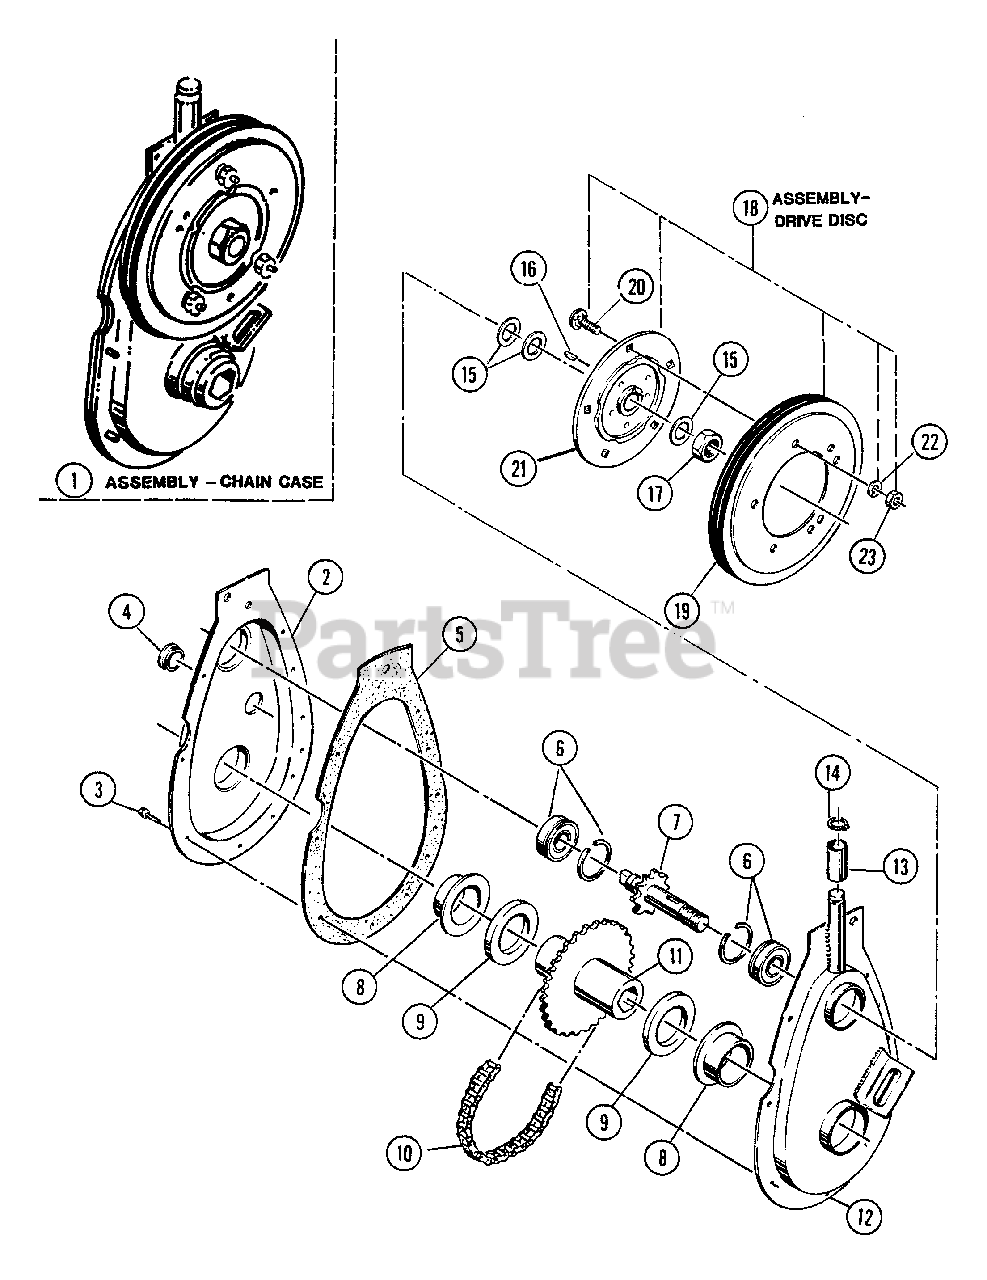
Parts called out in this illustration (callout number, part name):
1	ASSEMBLY, Chain Case
2	COVER, Sprocket
3	SCREW, #10-24 x 1/2" Hex Washer Self-Tap (Torx)
4	PLUG, Oil Fill & Check
5	GASKET
6	BEARING, Ball
7	SHAFT & SPROCKET
8	BUSHING
9	WASHER, Thrust
10	CHAIN
11	HUB & SPROCKET
12	CASE, Sprocket
13	ROLLER
14	RING, 1/2" External Retaining (Heavy Duty)
15	WASHER, 5/8" Belleville
16	KEY, 1/8 x 5/8 Woodruff
17	NUT, 5/8-18 Hex Center Lock
18	ASSEMBLY, Drive Disc
19	DRIVEN DISC
20	BOLT, 5/16-18 x 3/4" Square Neck Carriage, Grade 2A
21	HUB
22	WASHER, 5/16 Split Lock
23	NUT, 5/16-18 Hex, Grade B or 5
